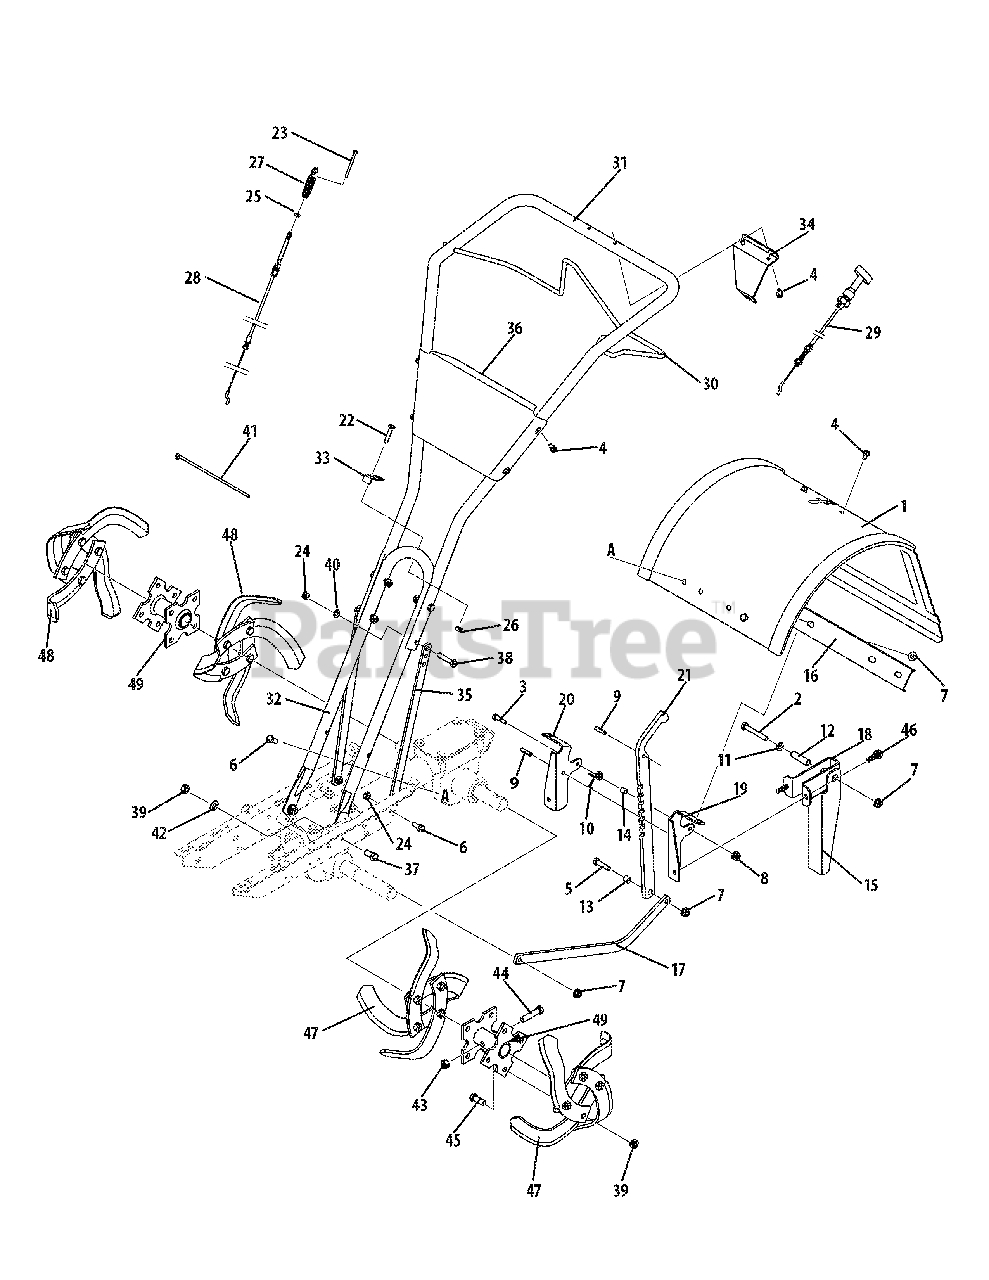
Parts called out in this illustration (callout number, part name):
2	Hex Screw, 5/16-18 x 2.25
3	Hex Head Screw, 1/4-20 x 1
4	Self-Tapping Screw, 1/4-20 x 1/2
5	Hex Head Screw, 5/16-18 x 1-1/4
6	Hex Head Screw, 5/16-18 x .75
7	Nylon Hex Lock Nut, 5/16-18
8	Nylon Hex Lock Nut, 1/2-20
9	Spirol Pin
10	Depth Regulator Spring
11	Flat Washer, 5/16
12	Spacer, .462 x .328 x 1.63
13	Bushing
22	Hex Hd. Screw, 1/4-20 x 1-1/4
23	Screw, #10-24 x 2
24	Hex Lock Nut, 5/16-18
25	Hex Nut, #10-24
26	Hex Lock Nut, 1/4-20
27	Forward Clutch Spring
28	Forward Clutch Cable Assembly
29	Rev. Clutch Cable Assembly
30	Forward Clutch Bail
37	Hex Screw, 3/-16 x 3/4
38	Hex Screw, 5/16-18 x 1-1/2
39	Hex Lock Nut, 3/8 -16
40	Lock Washer, 5/16
41	Cable Tie
42	Flat Washer, 3/8
43	Flange Lock Nut, 3/8-16
44	Hex Hd. Screw, 3/8-16 x 1-3/4
45	Hex Hd. Screw, 3/8 -16 x 1
46	Flange Screw, .312-18 x 1.00
